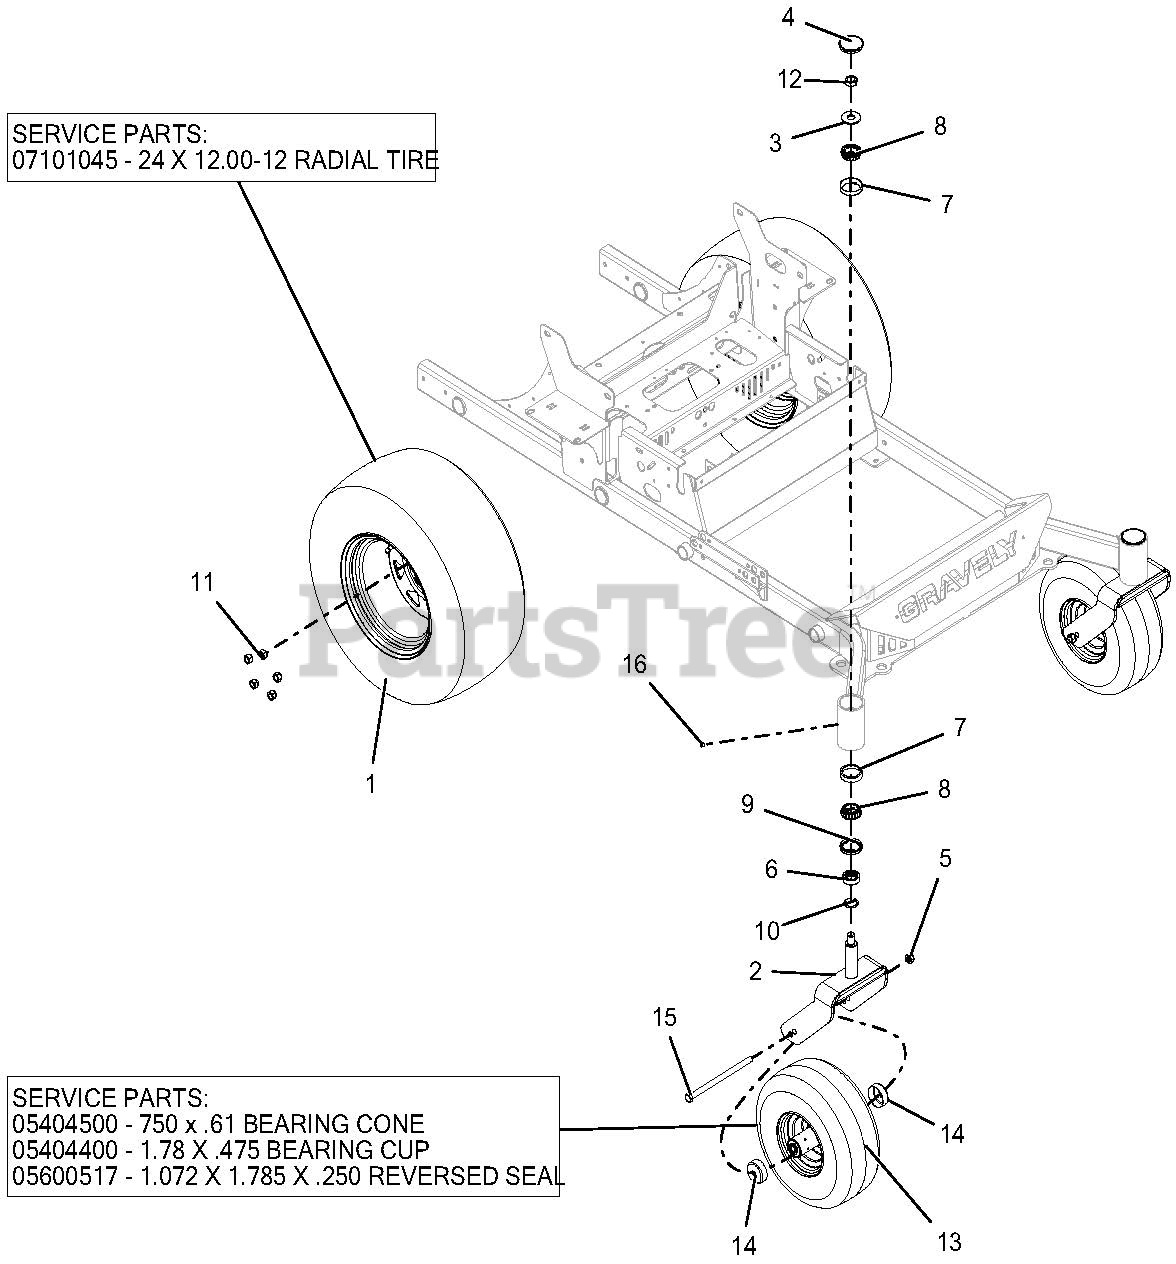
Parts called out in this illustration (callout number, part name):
1	TIRE/WHEEL, ASM 24 X 12-12 RADIAL
1	24 X 12.00-12 RADIAL TIRE
2	WMT, CASTER FORK - RED
3	WSHR-FL-STL.812X2.00X.148YWZC
4	CAP, DUST
5	NUT, LK-TOP-FLG .50-13 YWZC
6	SPCR, FRONT CASTER FORK
7	BRG, CUP 2.328 X .465
8	BRG, CONE 1.250 X .660
9	SEAL, OIL 1.75 X 2.332 X .312
10	O-RING, .139 W X 1.234 ID
11	NUT, LUG .500-13
12	@NUT-LK-TOP-JAM .75-16 YWZC
13	TIRE/WHEEL, 15 X 6.00-6 SEMI-PNEU
13	750 X .61 BEARING CONE
13	1.78 X .475 BEARING CUP
13	1.072 X 1.785 X .250 REVERSED SEAL
14	SHIELD, WHEEL BEARING
15	BLT-HEX .50-13X9.00 GR5 YWZC
16	FITTING, .250-28 FLUSH MOUNT GREASE
